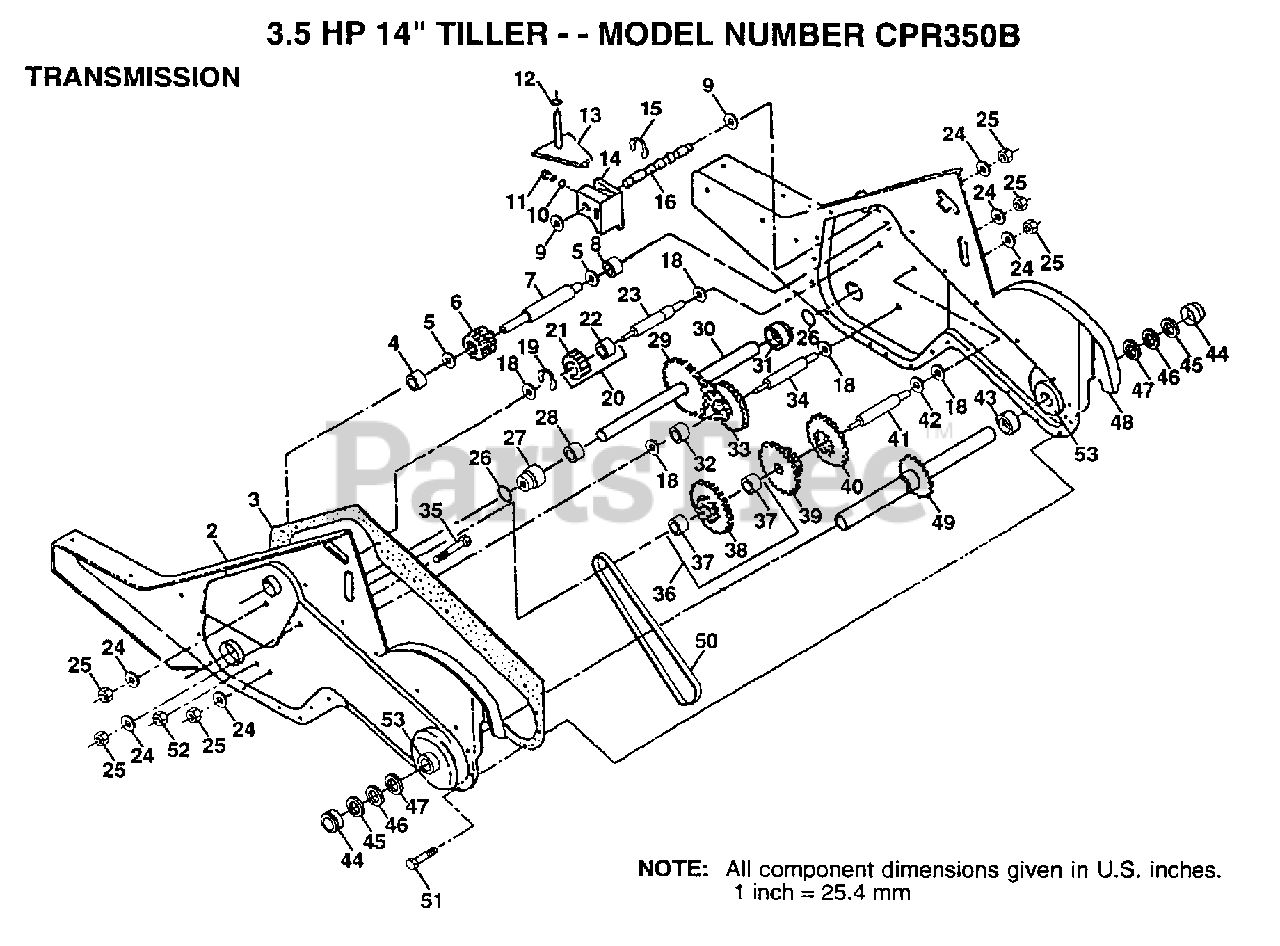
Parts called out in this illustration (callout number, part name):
2	No Desciption for Part
3	GASKET TI
4	NEEDLE BRNG LT
5	"T, BEARING"
6	GEAR PINION INPUT
7	SHAFT-INPUT CRT
8	"TI, BEARING"
9	WASHER SEAL CRT
11	SPRING-SHIFT CRT
12	O-RING TI
13	BRACKET ASM SHIFT
14	SHIFT FORK TI
15	KLIP RING
16	SHAFT.SHIFT.4.250
18	WASHER
19	KLIP RING
20	GEAR ASSY CRT
21	GEAR-REV IDLR CRT
22	NEEDLE BEARING TI
23	SHAFT CRT
24	LOCKWASHER
25	NUT.ASF.HEX.7/16
26	O RING CRT
27	"CRT, BEARING"
28	BUSHING TI
29	CHAIN CRT
32	SPACER TI
33	SPRCKT 8 GEAR CRT
34	SHFT 2ND RED. CRT
35	SCRW WHIZ LOK CRT
36	SPROCKET ASM.
37	BEARING
39	GEAR TI
40	GEAR TI
41	REDUCTION SHFT TI
42	BRNG RACE
43	SPACER TI
44	CUP.FORMED.
45	RING SPIRAL CRT
46	SEAL RING RUBBER
47	OIL SEAL STD
49	TINE SHAFT
50	CHAIN.50 LINK TI
51	SCREW CRT
52	NUT.HEX.5/16-18
